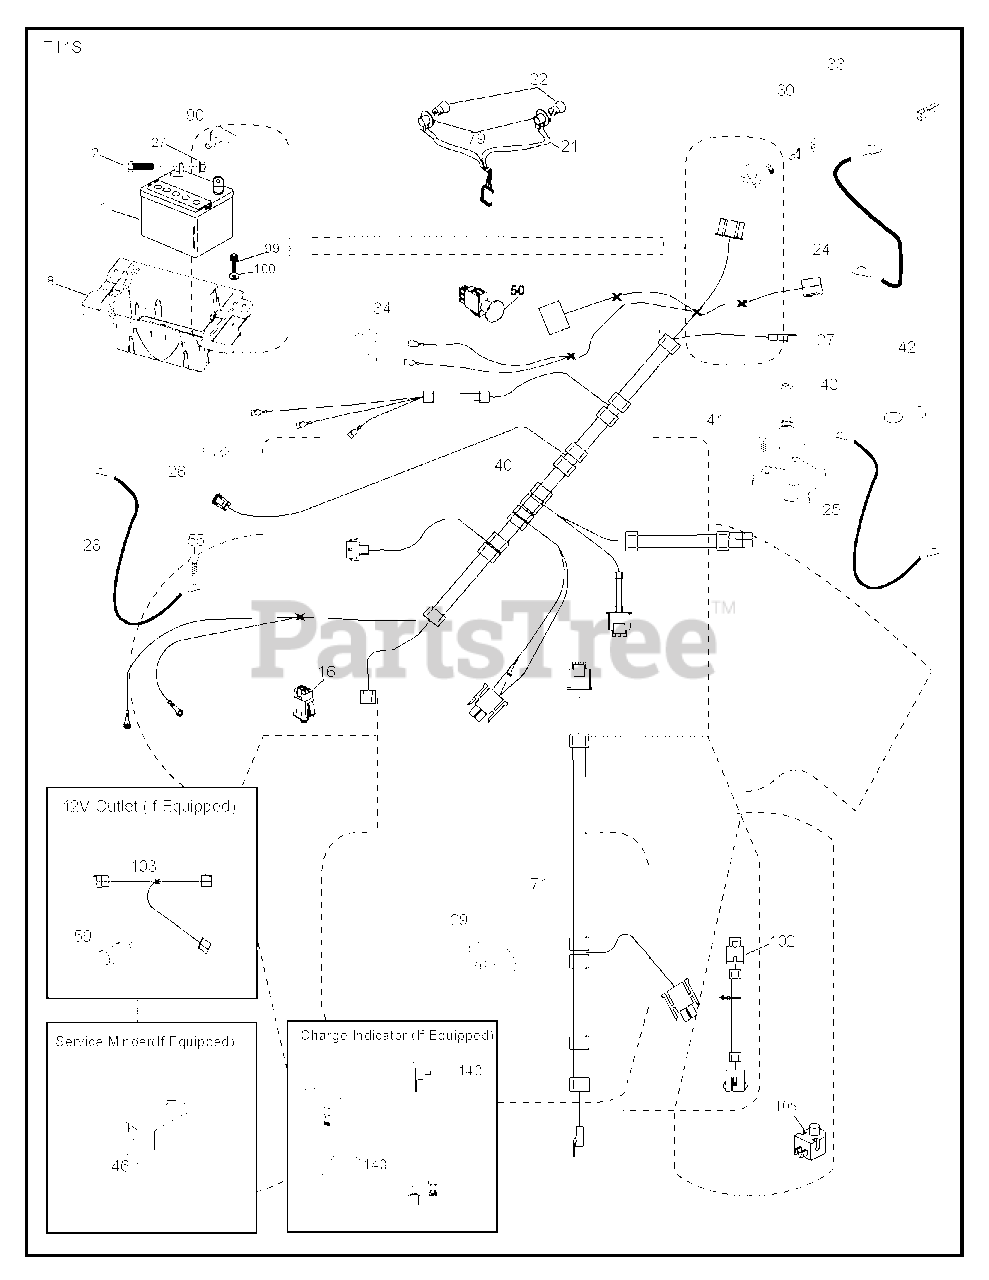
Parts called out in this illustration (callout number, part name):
1	Battery, Dry 30 Amp
2	BOLT.HEX.1/4.X.3/4.DICHROMATE
8	TRAY.BATTERY BOX.FRONT
16	SWITCH INTERLOOK PUSH-IN
21	HARNESS.LIGHT W/4152J BULBS
24	CABLE.FRBATT.W/WIRE.8GA.8
25	CABLE.STARTER.8GA.17.5
26	FUSE 20AMP
27	NUT
28	CABLE.GROUND.21"BLK.8GA.90T
29	SWITCH.SEAT.DELTA.OPC.
30	SWITCH.IGN.DELTA.W.LGH.ROS
33	KEY.CHAIN.BLISTER.PACK.GEN.USA
40	HARNESS HARNESS..DASH.ING.ELEC
41	SCREW
42	TERMINAL COVER
43	SOLENOID.STARTER.BRASS.PLUNGER
46	GUAGE.SRVCMNDR.HRMTR.
50	SWITCH.PTO.8TERMINAL.STD.BLK
55	SCREW 5/16"
71	HARNESS-CHASSIS SUB
79	BULB HOLDER ASM.
90	COVER.TERMINAL.BATTERY
99	SCREW HEXWSHR 1/4-20X3/4
102	HARNESS PIGTAIL PCH TEX ROS
105	REVERSE SWITCH
